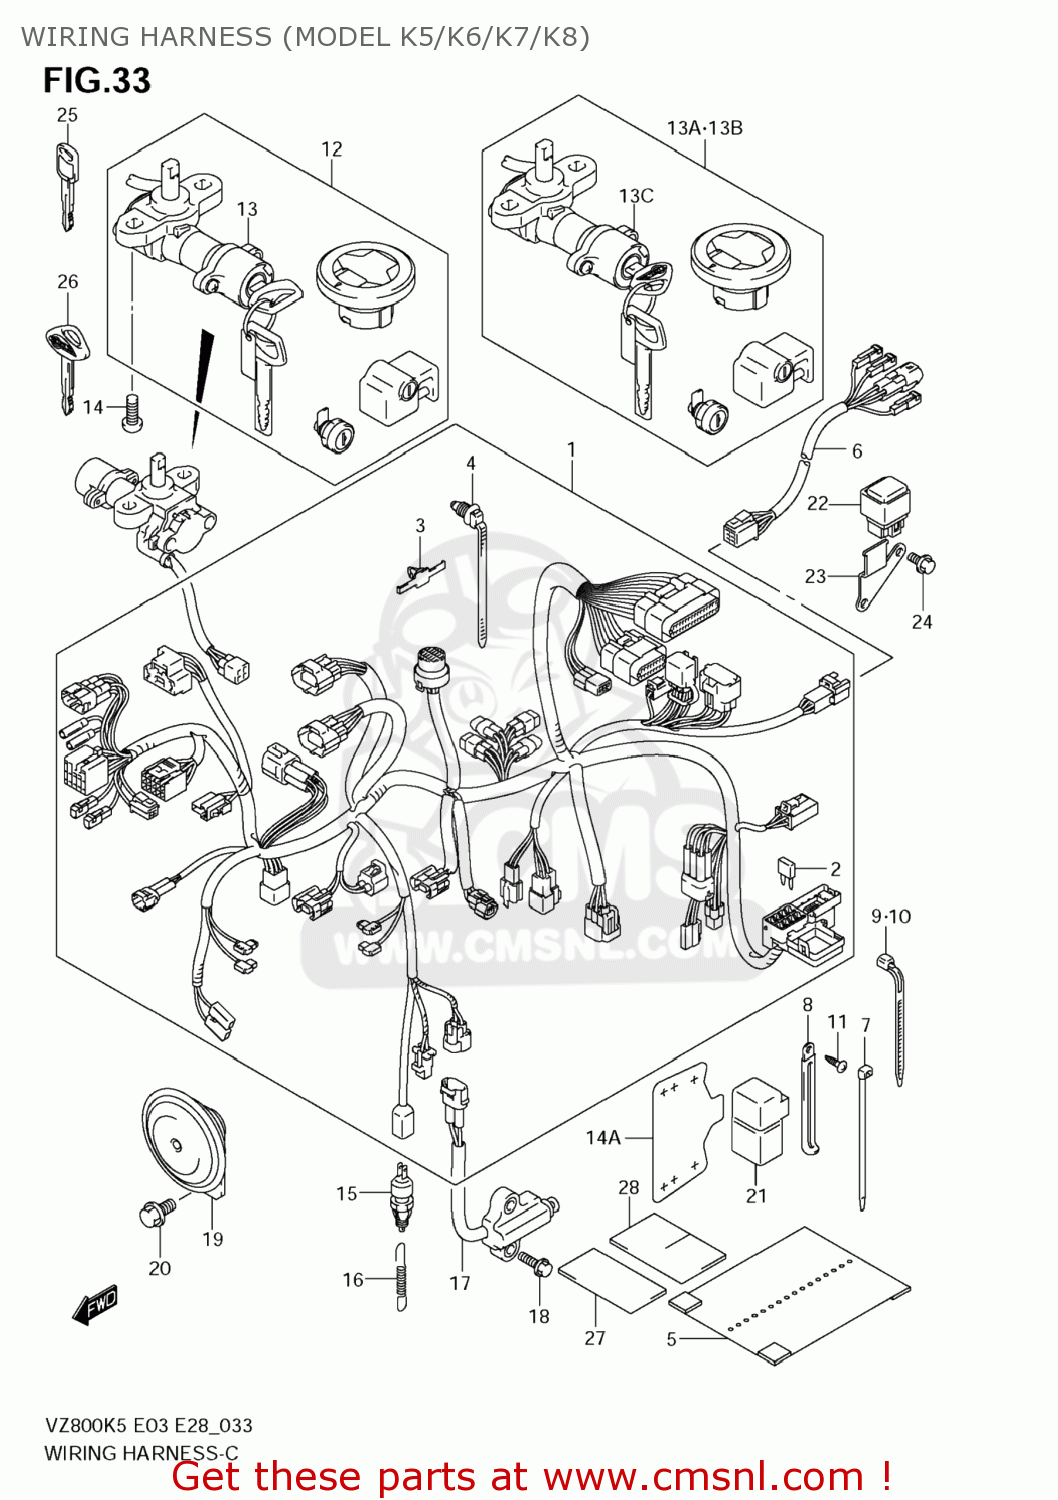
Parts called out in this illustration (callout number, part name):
1	HARNESS, WIRING (MODEL K5 E3,E28,E33MODEL K6 E3,E28)
2	FUSE(10A)
3	CLAMP
4	CLAMP(L:154)
5	COVER,WIRING HARNESS
6	WIRE,REAR COMB
7	CLAMP(L:145)
8	CLAMP(L:80)
9	CLAMP(L:165)
10	CLAMP(L:190)
11	SCREW
12	LOCK SET
13	LOCK ASSY,STEERING
13A	LOCK SET
13B	LOCK SET
13C	LOCK ASSY,STEERING
14	BOLT(8X20)
14A	PROTECTOR,IGNITION SWITCH
15	SWITCH ASSY,STOP LAMP
16	SPRING
17	SWITCH ASSY,SIDE STAND
18	BOLT
19	HORN ASSY
20	BOLT
21	RELAY ASSY
22	RELAY ASSY
23	BRACKET,HEADLAMP RELAY
24	BOLT
25	KEY,BLANK
26	KEY,BLANK(BOULEVARD)
27	TAPE,WIRING HARNESS(28X50X0.13
28	PROTECTOR,HARNESS(30X50X3)
